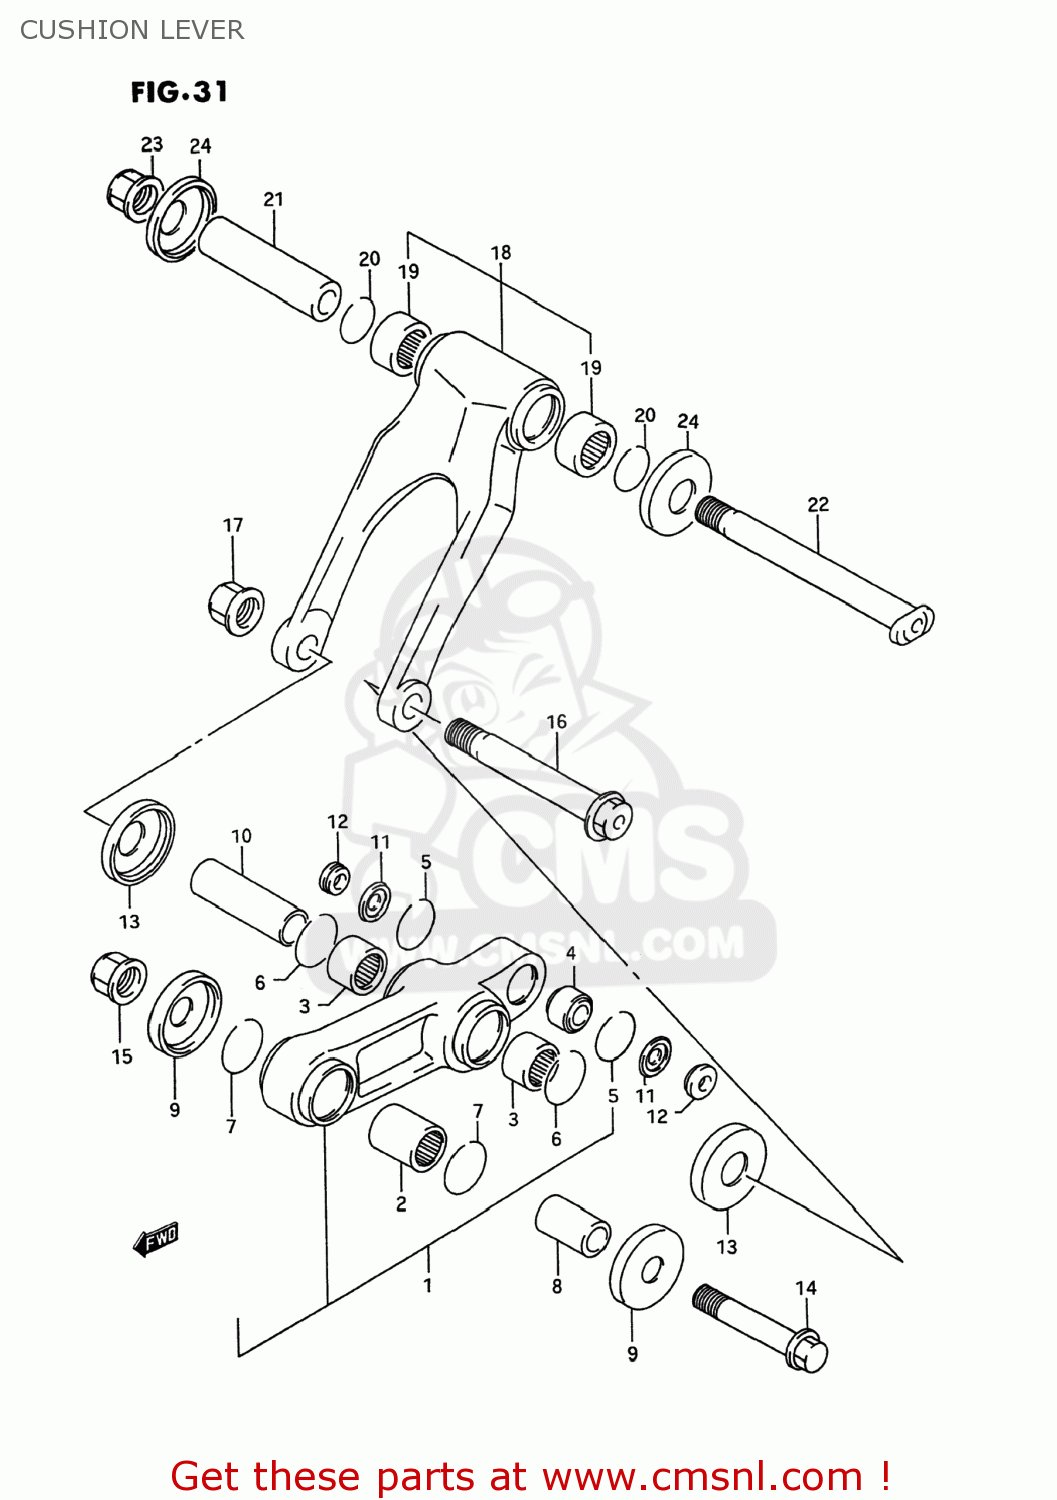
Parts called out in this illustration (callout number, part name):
1	LEVER SET,RR CUSHION
2	BEARING(20X27X25)
3	BEARING(22X28X20)
4	BEARING,RR CUSHION LEVER RR
5	RING,BEARING STOPPER
6	CIRCLIP
7	CIRCLIP
8	SPACER,RR CUSHION LEVER FR
9	SEAL,REAR CUSHION LEVER
10	SPACER,RR CUSHION LEVER CTR
11	SEAL,RR CUSHION LEVER RR DUST
12	SPACER,RR CUSHION LEVER RR
13	SEAL,RR CUSHION LEVER CTR
14	BOLT,RR CUSHION LEVER FR
15	NUT 12MM
16	BOLT,REAR CUSHION LEVER
17	NUT
18	ROD SET,RR CUSHION LEVER
19	BEARING(22X28X20)
20	CIRCLIP
21	SPACER,RR CUSHION ROD
22	BOLT,RR CUSHION ROD
23	NUT
24	SEAL,RR CUSHION LEVER CTR
